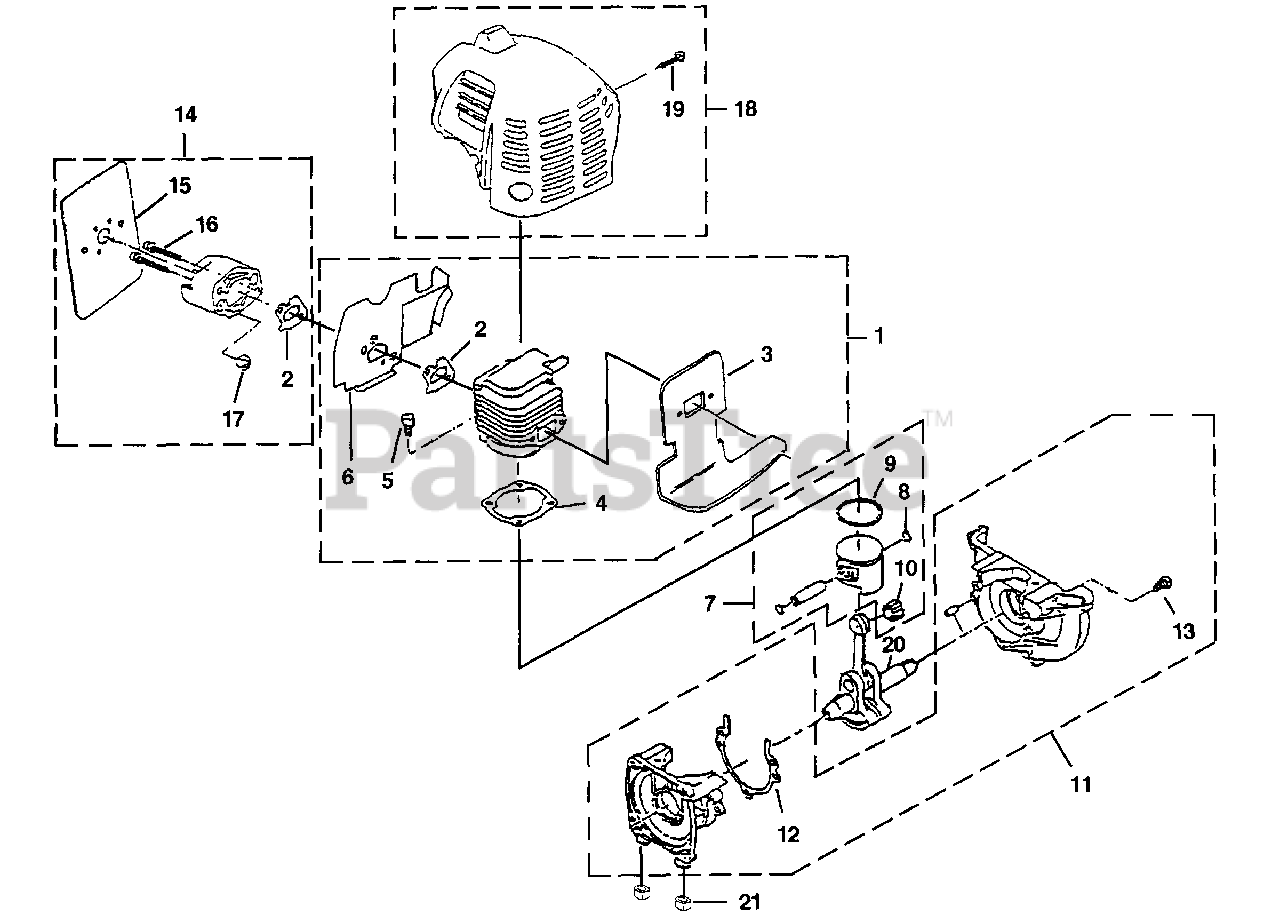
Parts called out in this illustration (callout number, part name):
1	CYLINDER ASSEMBLY
2	GASKET - Heat Dam
3	GASKET - Muffler
4	GASKET - Cylinder
5	SCREW - Socket HD (M5 x 20 SW)
6	INSULATOR - Carburetor
7	PISTON ASSEMBLY
8	RING - Retaining
9	RING - Piston
10	BEARING - Wrist Pin
11	CRANKCASE ASSEMBLY
12	GASKET - Crankcase
13	SCREW (M5 x 25)
14	HEAT DAM ASSEMBLY W/Nuts
15	GASKET - Carburetor
16	SCREW - Socket Hd
18	CYLINDER COVER
19	SCREW (M5 X 14)
20	CRANKSHAFT
21	RUBBER BUMPER KIT
